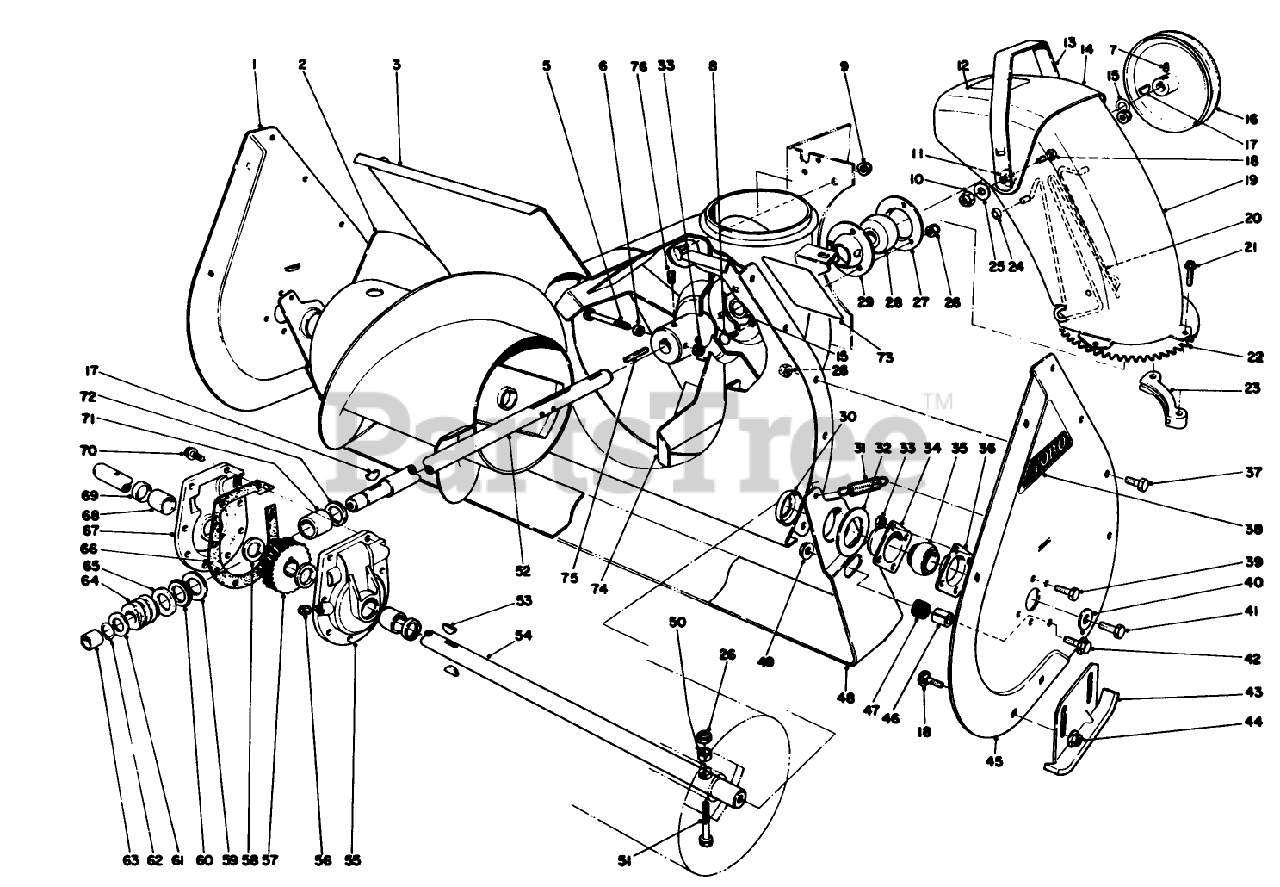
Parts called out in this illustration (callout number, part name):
1	RH AUGER SIDE PLT R
2	Auger Right
3	AUGER HSG WA RO
5	SCREW-HHF
6	SPACER
7	SCREW-SET, SQH
8	BOLT-CARR
9	NUT-LOCK, NI
10	NUT-LOCK, CONE
11	WASHER-RUBBER
12	DECAL-DANGER DISCH.
13	DEFLECTOR HANDLE B
14	Deflector Chute (Incl. Ref. #12)
15	WASHER
16	IMPELLER PULLEY
17	KEY-WOODRUFF
18	SCREW-CARR
19	CHUTE B
20	CHUTE WIRE
21	SPECIAL SCREW
22	Gear-Chute Swivel
23	CHUTE RETAINER
24	NUT-PUSH
25	WASHER-BELLEVILLE
26	NUT-LOCK, NI
27	Bearing-Flange Rear
28	BEARING-BALL
29	Bearing-Flange, Front
30	Positioner-Scraper
31	SPRING-TENSION
32	SCRAPER BLADE SPACER
33	NUT-HEX
34	BEARING-FLANGE, FRONT
35	BEARING
36	BEARING-FLANGE, REAR
37	SCREW-HHF
38	AUGER SIDE PLT DECAL
39	SCREW-HH
40	WASHER
41	SCREW-HH
42	SCREW-HHF
43	AUGER SKID WA R
44	NUT-HHF, WHIZ
45	LH AUGER SIDE PLT R
46	SCRAPER STOP SPACER
47	SCRAPER STOP CUSHION
48	24 SCRAPER BLD
49	NUT-HF
50	SPACER-HUB, AUGER
51	Auger Bolt
52	IMPELLER SHAFT
53	KEY-WOODRUFF
54	24 AUGER SHAFT
55	Case-Gear (Incl. Ref. #68 & 69)
56	PLUG-PIPE, SQH
57	GEAR-WORM, 27T
58	WASHER-THRUST
59	WASHER-THRUST
60	BEARING-THRUST
61	WASHER-THRUST
62	Ring-Snap
63	BUSHING
65	THRUST-WASHER
66	GASKET-CASE, GEAR
67	Gear Case (Incl. Ref. #68 & 69)
68	BUSHING
69	SEAL-OIL
70	SCREW-TAPTITE
71	BUSHING-SPECIAL
72	RING-QUAD
73	DECAL-WARNING, AUGER
74	IMPELLER WA B
76	SCREW-SET, SQH
